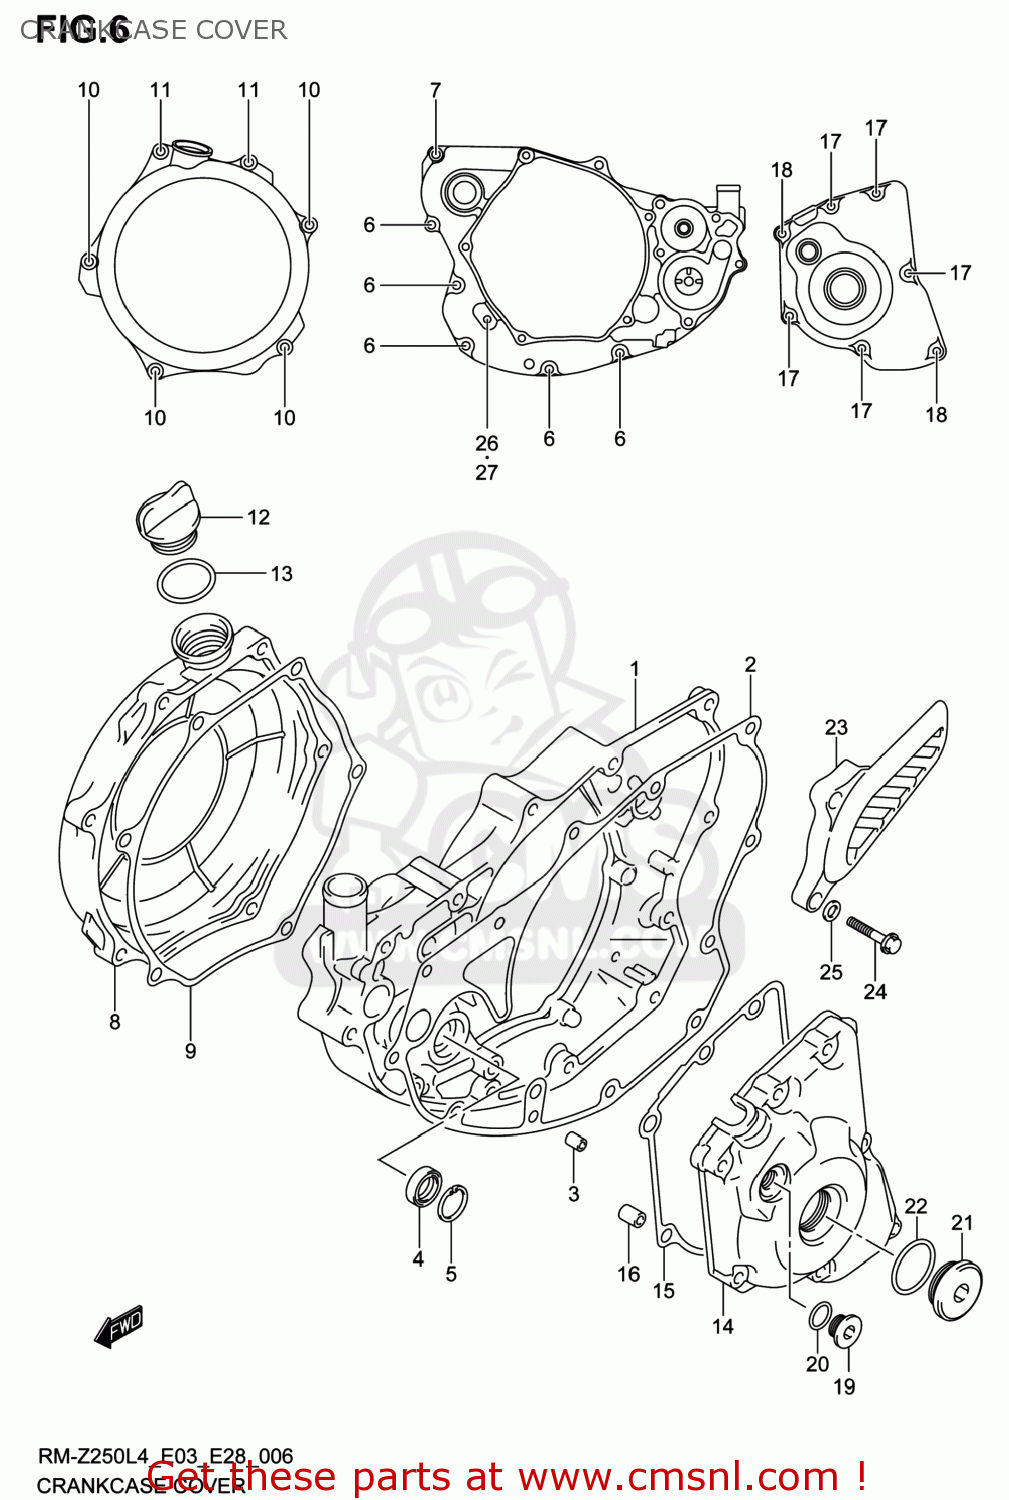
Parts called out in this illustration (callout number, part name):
1	COVER,CLUTCH
2	GASKET,CLUTCH COVER (NAS)
3	PIN
4	SEAL,OIL(12X22X6)
5	CIRCLIP
6	BOLT
7	BOLT
8	COVER,CLUTCH OUTER
9	GASKET,CLUTCH COVER OUTER (NAS)
10	BOLT
11	BOLT
12	PLUG
13	O RING(D:3.1,ID:16.8)
14	COVER,MAGNETO
15	GASKET,MAGNETO COVER (NAS)
16	PIN
17	BOLT
18	BOLT
19	PLUG(12X9)
20	O RING(D:1.9,ID:9.8)
21	PLUG(26X9)
22	O RING(D:3.1,ID:22.7)
23	COVER,ENGINE SPROCKET
24	BOLT
25	WASHER
26	BOLT
27	GASKET(5.8X13X1.2) (NAS)
